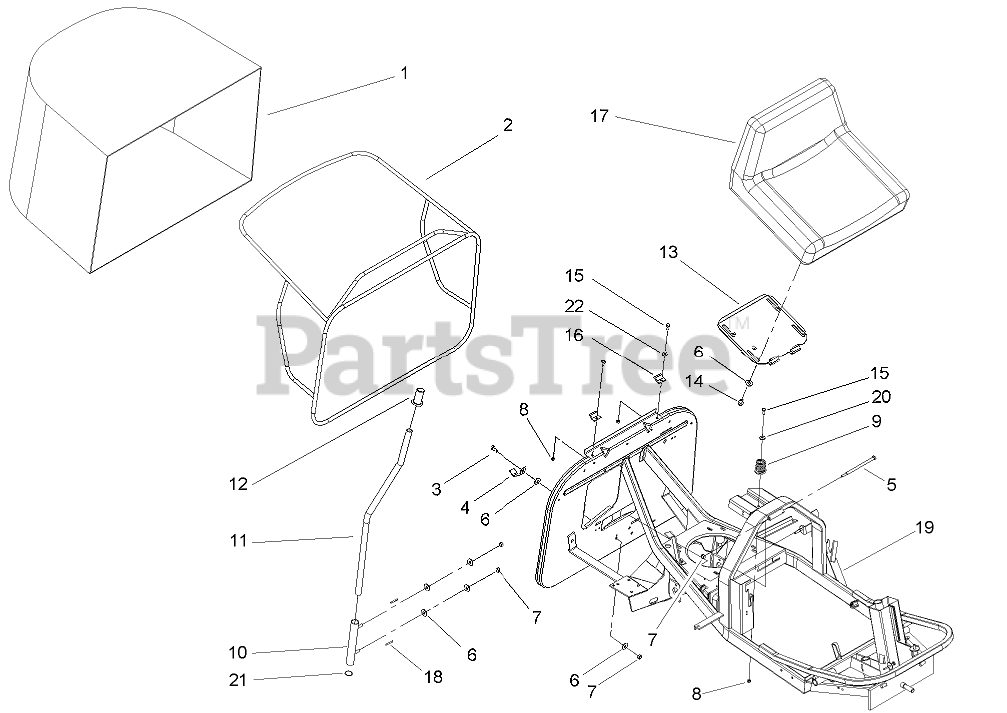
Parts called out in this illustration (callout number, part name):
1	BAG-GRASS
2	Frame-Bag
3	SCREW-HH
4	Hook-Bag
5	Screw-HH
6	Washer-Flat
7	NUT-LOCK
8	NUT-LOCK
9	Spring-Compression
10	Support
11	Lever
13	Plate-Seat
14	SCREW-HHF
15	SCREW-HH
18	Pin-Spring
20	Washer-Flat
21	Spacer
22	Washer-Flat
